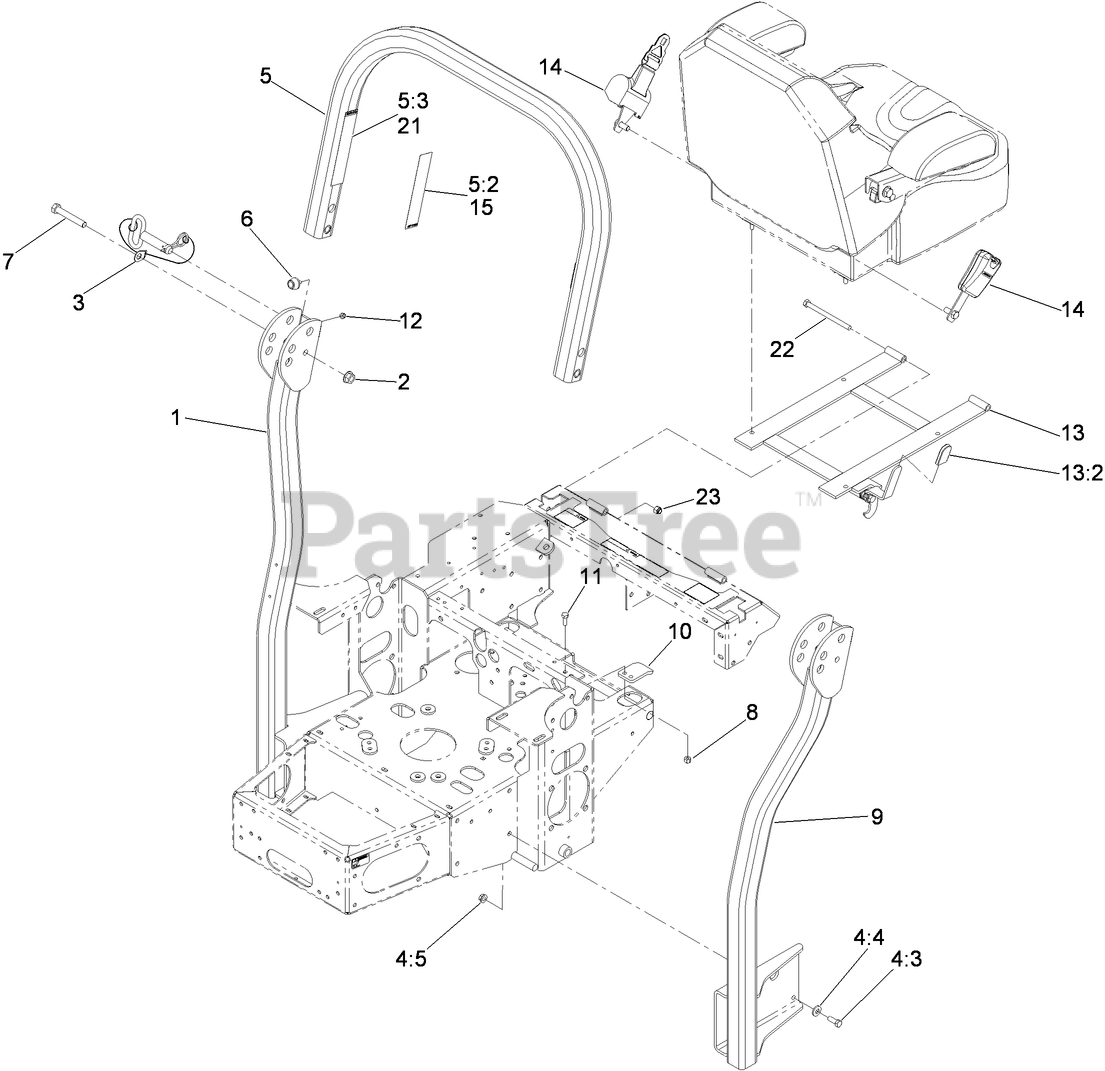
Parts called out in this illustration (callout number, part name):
1	LH TUBE SUPPORT ASM
2	NUT-HF
3	PIN-FOLD, ROPS
4	BAG-BOLT, ROPS
4:3	SCREW-HH
4:4	WASHER-BELLEVILLE
4:5	NUT-HHF, WHIZ
5	Upper Tube ASM
5:3	DECAL-WARNING, FOLDING ROPS
6	BUMPER-RUBBER
7	SCREW-HH
8	NUT-LOCK, NI
9	RH TUBE SUPPORT ASM
10	CATCH-LATCH, SEAT
11	SCREW-HH
12	NUT-LOCK, NI
13	SEAT FRAME AND LATCH ASM
13:2	GRIP-LEVER
14	SEAT BELT KIT
15	DECAL-WARNING
21	DECAL-WARNING, FOLDING ROPS
22	SCREW-HH
23	NUT-LOCK, NI
